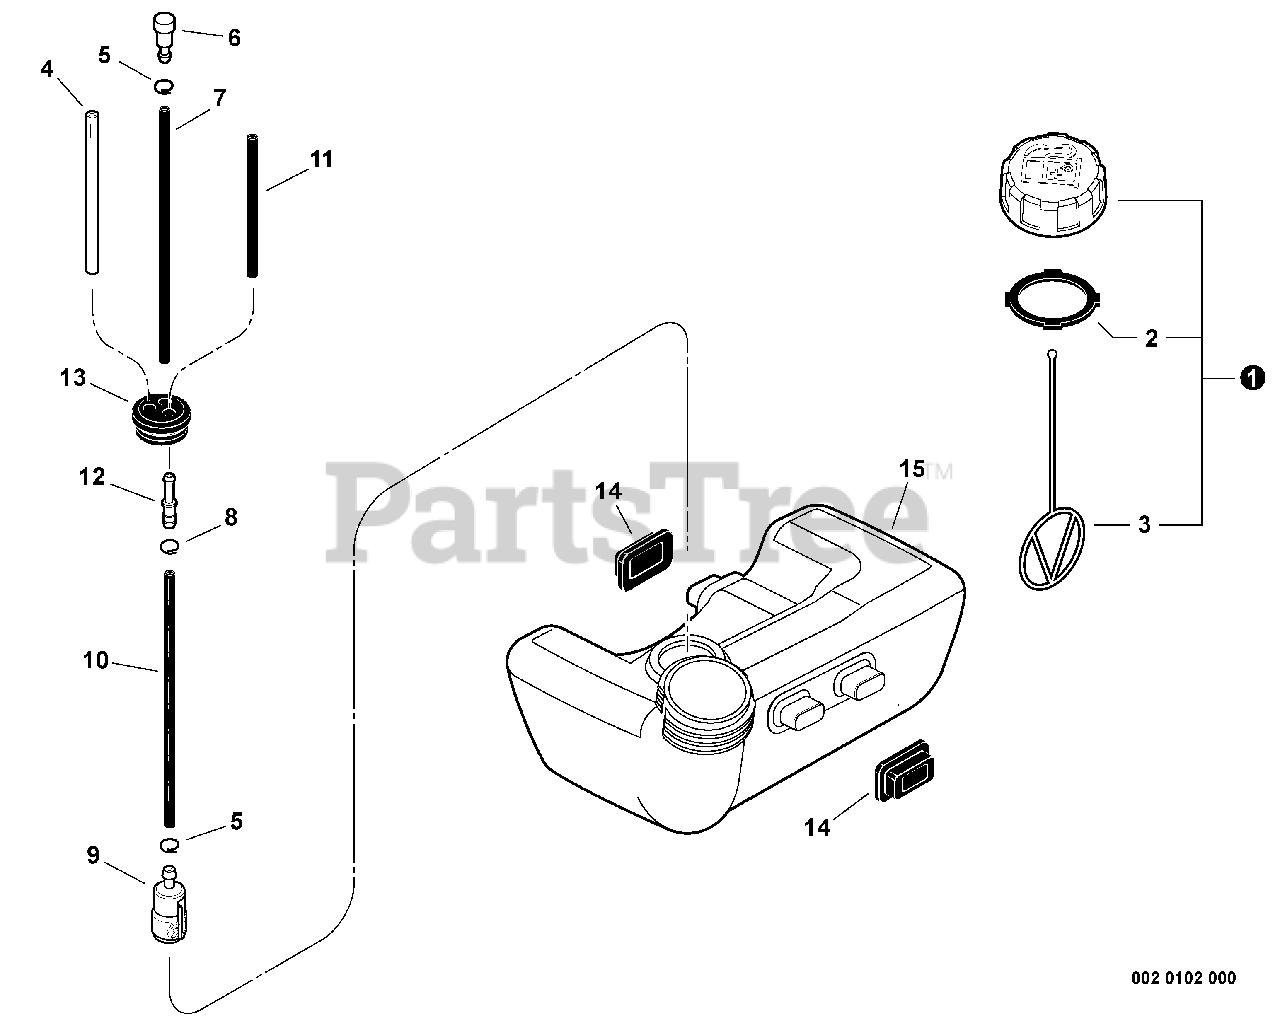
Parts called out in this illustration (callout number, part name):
1	CAP ASSY - RED
2	GASKET, CAP
3	CONNECTOR, CAP
4	PIPE - 3X6X80 -- CLEAR
5	CLIP - 6
6	VENT, FUEL TANK
7	PIPE - 3X6X90 -- BLACK
8	CLIP - 6.5
9	FILTER, FUEL
10	PIPE - 3X6X120 -- BLACK
11	PIPE - 3X5X67 -- BLACK
12	CONNECTOR, PIPE
13	GROMMET
14	CUSHION, FUEL TANK
15	TANK, FUEL
